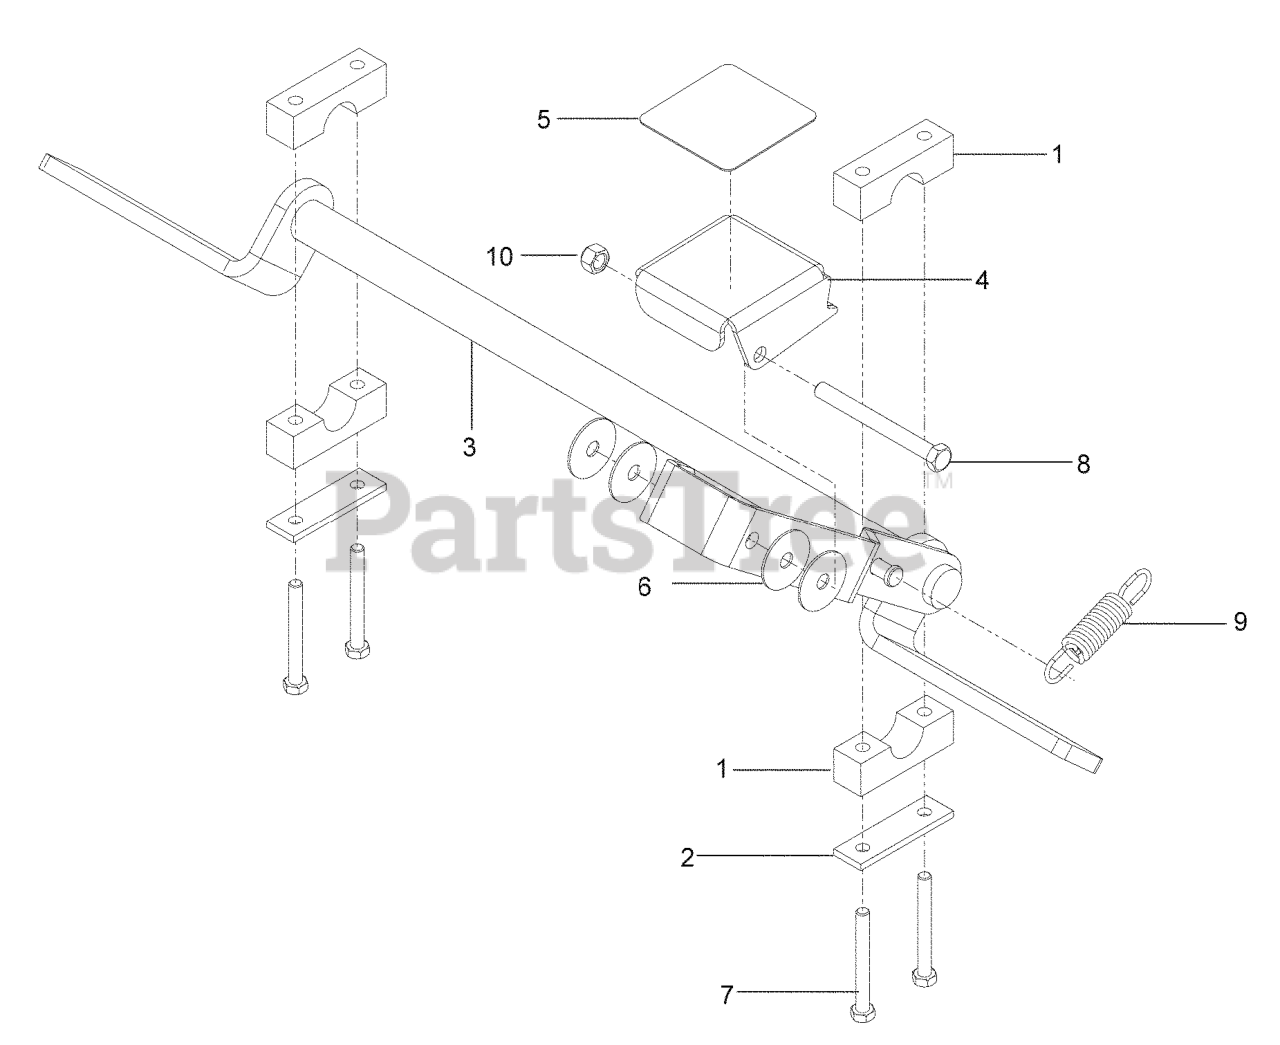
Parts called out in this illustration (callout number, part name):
1	PILLOW BLOCK
2	REINFORCEMENT BAR
3	PARK BRAKE
4	PEDAL, BLACK
5	ANTI-SKID PAD
6	WASHER, FRICTION
7	HCS 5/16C X 2-3/4
8	HCS3/8-16.X
9	SPRING, EXTENSION
10	NUT 3/8-16 NYLOC
